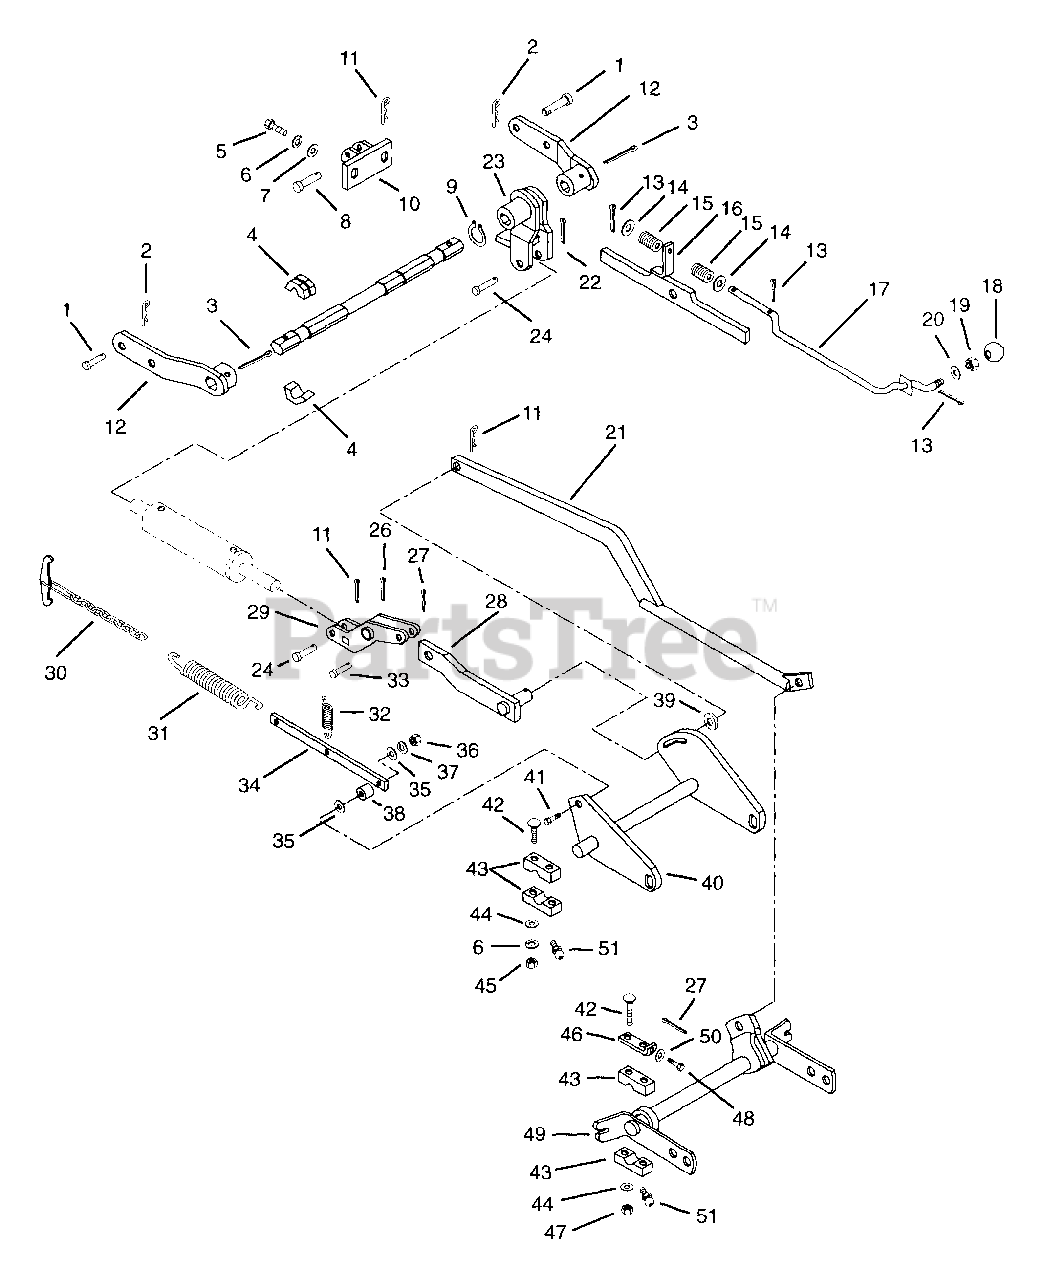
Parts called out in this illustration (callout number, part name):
1	PIN-CLEV .50X1.25 RH ST PL
2	PIN-HAIR INT .14X.4X2.75
3	PIN-COTR .18X2.0 ZCC
4	BSHG-FLG 1.000X1.750X1.000
5	BLT-HEX .38-16X1.00 PL
6	WSHR-LK .375X.094 MED PL
7	WSHR-FL-STL .438X1.0X.083 PL
8	PIN-CLEV .619X2.0 YWZC
9	RG-RTNG-EXT 1.125X.050
11	PIN-HAIR INT .09X.188 PL
13	PIN-COTR .12X.75 PL
14	WSHR-FL-STL.406X.812X.065PL
15	SG-COMP .65X.56X1.50
17	LATCH ROD
18	KNOB-STEERING LOCK
19	NUT-JAM .375-16 PL
20	WSHR-FL-STL .406X1.00X.062 PL
21	LINK - CONNECTOR
22	PIN-COTR .12X1.0 PL
24	PIN-CLEV .494X1.94 YWZC
26	PIN-COTR .18X1.25 PL
27	PIN-COTR .18X1.0 PL
29	BELLCRANK
31	SG-TENS .156X1.062X8.68 WLD ??
32	SG-TENS .035X.45X2.75 WLD 3.5
33	PIN-CLEV .619X1.43 YWZC
35	WSHR-FL-STL.281X.62X.065 PL
36	NUT-HEX .250-20 PL
37	WSHR-LK .250X.077 HVY PL
38	SPACER .269X.375X.343
39	WSHR-FL-STL.812X1.500X.139
40	CENTER ROCKSHAFT
41	BLT-HEX .25-20X1.00 GR2
42	BLT-RDHDSQNK .38-16X2.25 SHTPL
44	WSHR-FL-STL .406X.750X.005
45	NUT-HEX .375-16
47	NUT-LK-CTR .375-16 GR A PL
48	BLT-HEX .31-18X1.25 PL GR5
49	ROCK SHAFT-FRONT
50	WSHR-LK .312X.097 PL HVY
51	FTG-LUBE .25-28X.256 YWZC
